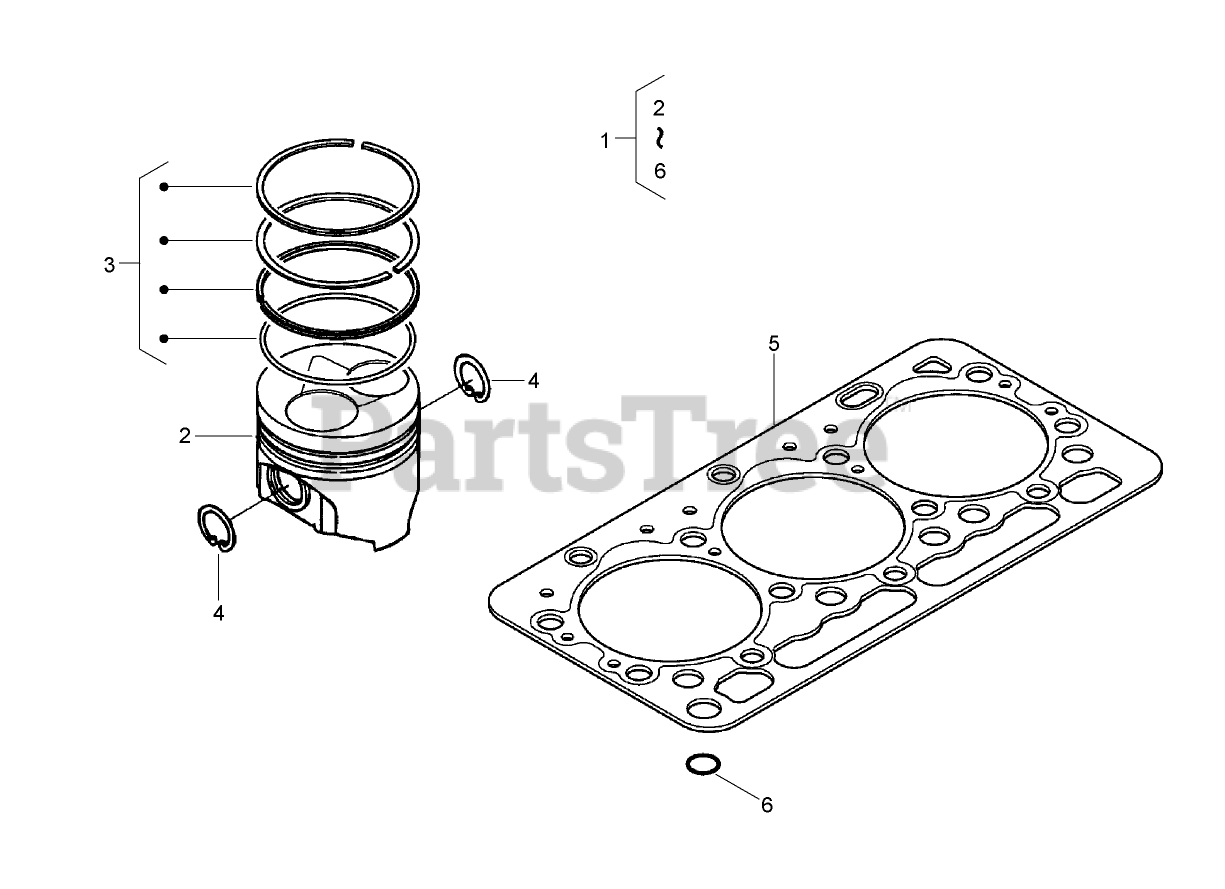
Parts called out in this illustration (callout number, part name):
1	PISTON KIT
2	PISTON STD
3	PISTON RING ASM (STD)
4	CIRCLIP-INTERNAL
5	GASKET-HEAD, CYLINDER
6	O-RING
